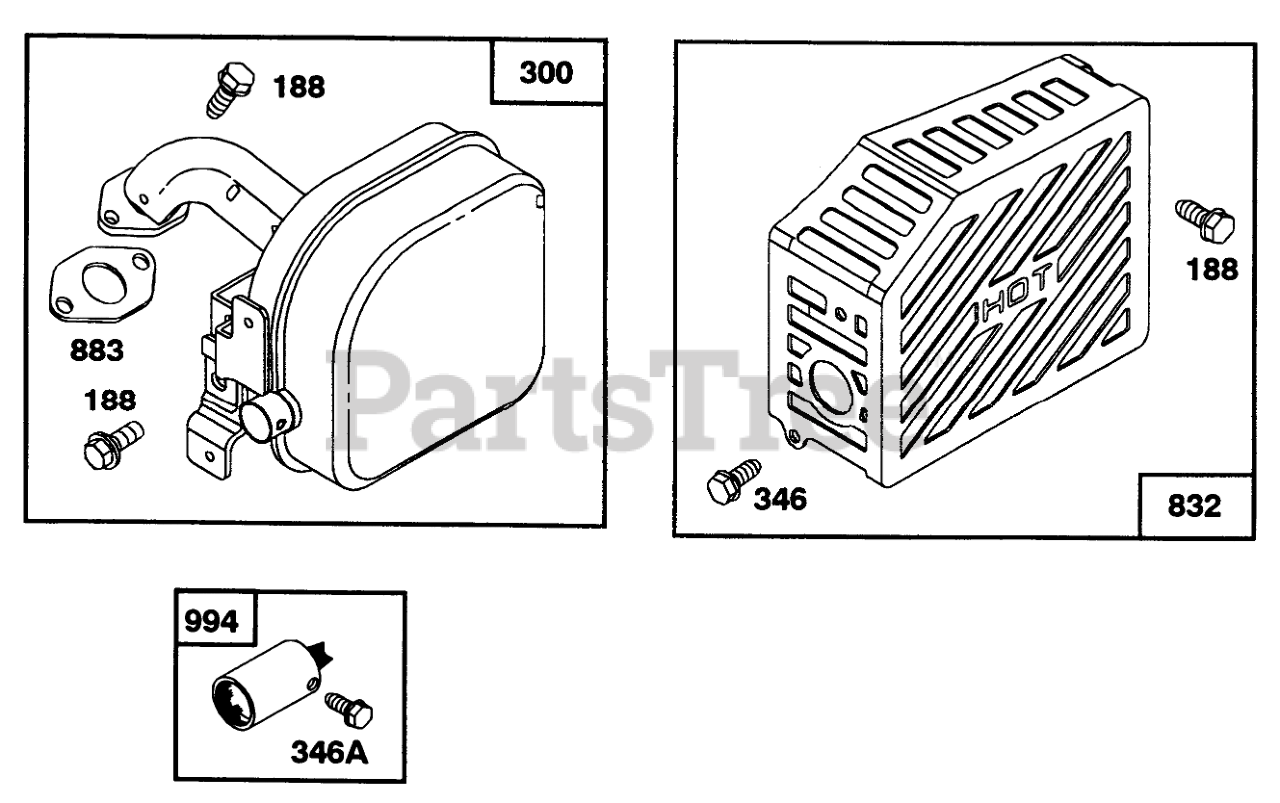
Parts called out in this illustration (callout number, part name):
188	SCREW - SEM
300	MUFFLER - EXHAUST
346	SCREW - SELF-TAPPING
346A	SCREW - ARRESTER MTG.
832	Guard-Muffler
883	EXHAUST GASKET
994	ARRESTER - SPARK
